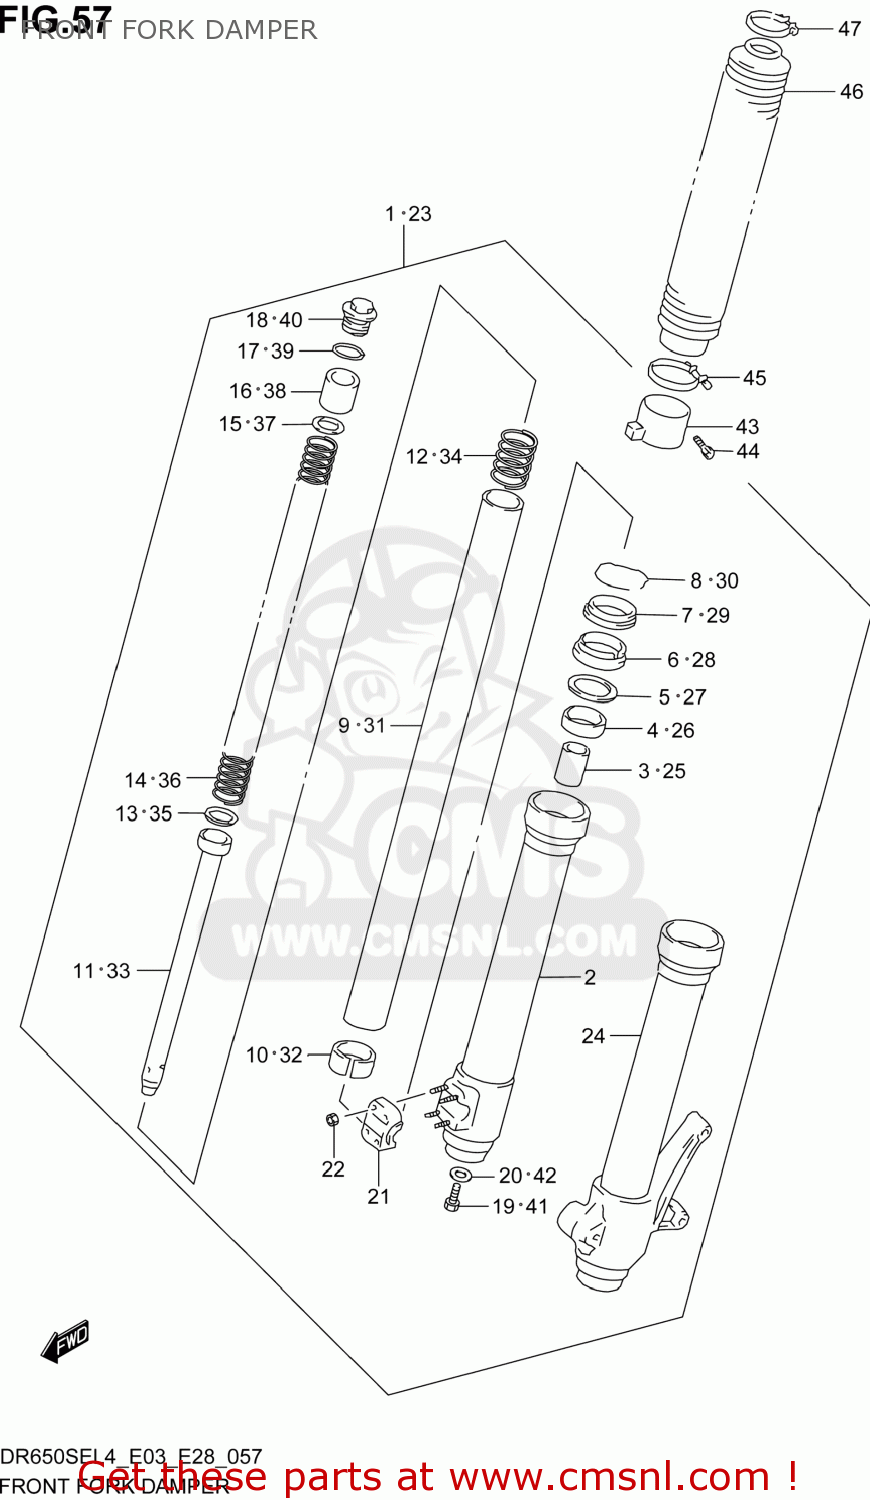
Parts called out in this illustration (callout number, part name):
1	DAMPER ASSY,FR FORK,R
2	TUBE,OUTER,R
3	PIECE,OIL LOCK
4	METAL,SLIDE
5	WASHER
6	SEAL,OIL
7	SEAL,DUST
8	RING,STOPPER
9	TUBE,INNER
10	PISTON
11	CYLINDER
12	SPRING,REBOUND
13	RING,PISTON
14	SPRING
15	WASHER
16	SPACER
17	O RING
18	CAP,FORK
19	BOLT,FORK CYLINDER(10X25)
20	GASKET (NAS)
21	HOLDER,AXLE,R
22	NUT
23	DAMPER ASSY,FR FORK,L
24	TUBE,OUTER,L
25	PIECE,OIL LOCK
26	METAL,SLIDE
27	WASHER
28	SEAL,OIL
29	SEAL,DUST
30	RING,STOPPER
31	TUBE,INNER
32	PISTON
33	CYLINDER
34	SPRING,REBOUND
35	RING,PISTON
36	SPRING
37	WASHER
38	SPACER
39	O RING
40	CAP,FORK
41	BOLT,FORK CYLINDER(10X25)
42	GASKET (NAS)
43	GUIDE,BOOT
44	BOLT
45	BAND,BOOT LWR
46	BOOT, BLACK
47	BAND,BOOT
